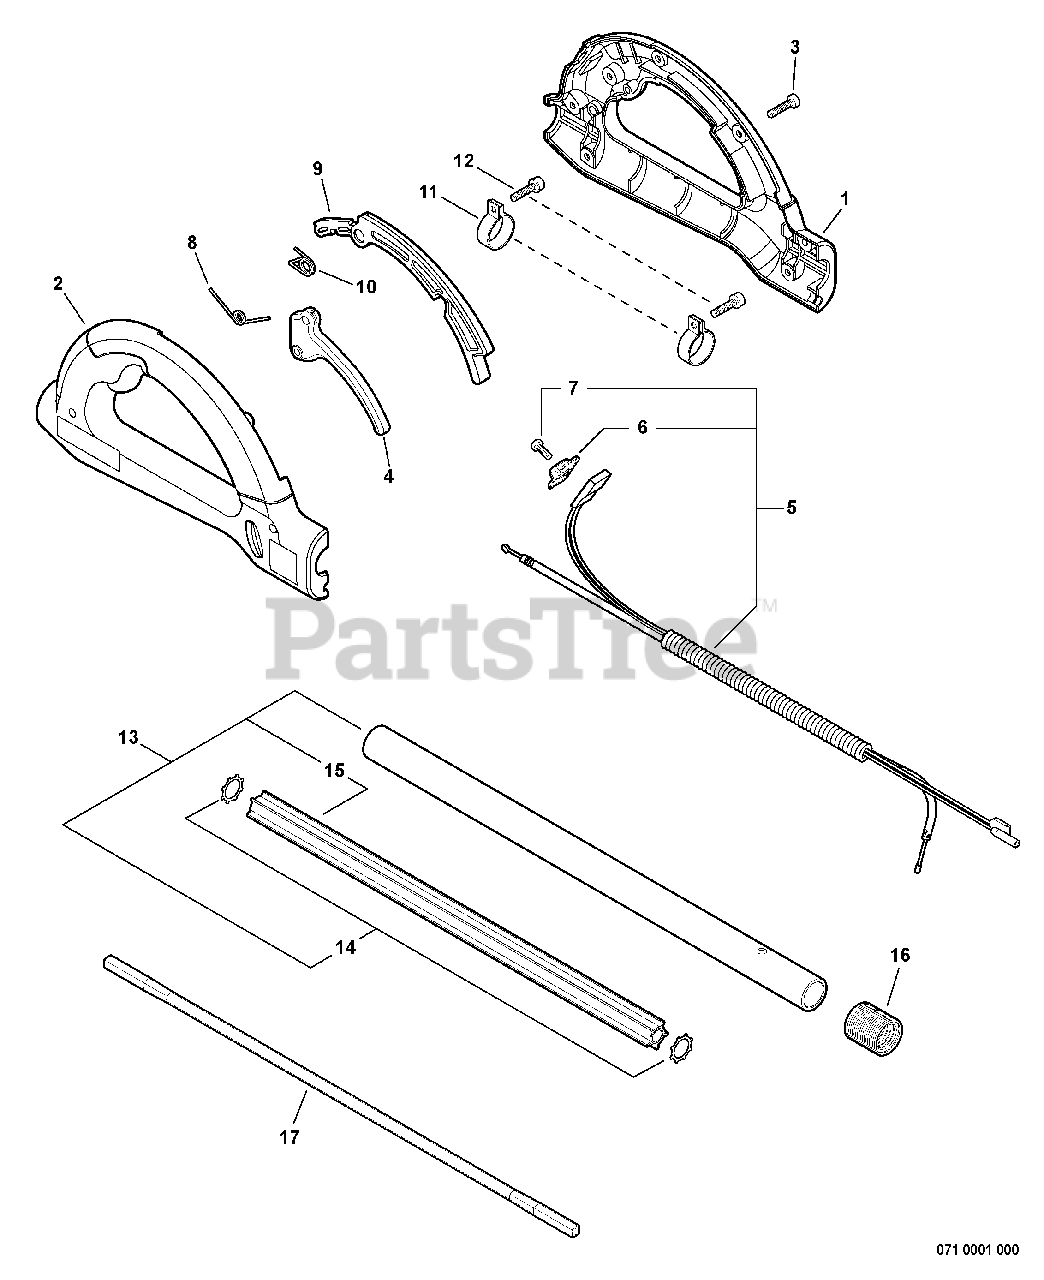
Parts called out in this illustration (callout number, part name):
1	HANDLE, RIGHT
2	HANDLE - LEFT
3	SCREW M5×18
4	TRIGGER, THROTTLE
5	CABLE ASSY, CONTROL
6	KNOB, SWITCH - ORANGE
7	SCREW 3×10
8	SPRING, TORSION
9	LOCKOUT, THROTTLE
10	SPRING, TORSION
12	SCREW M5×20
13	MAIN PIPE ASSY
16	TUBE, FLEXIBLE
17	DRIVESHAFT - FLEXIBLE
